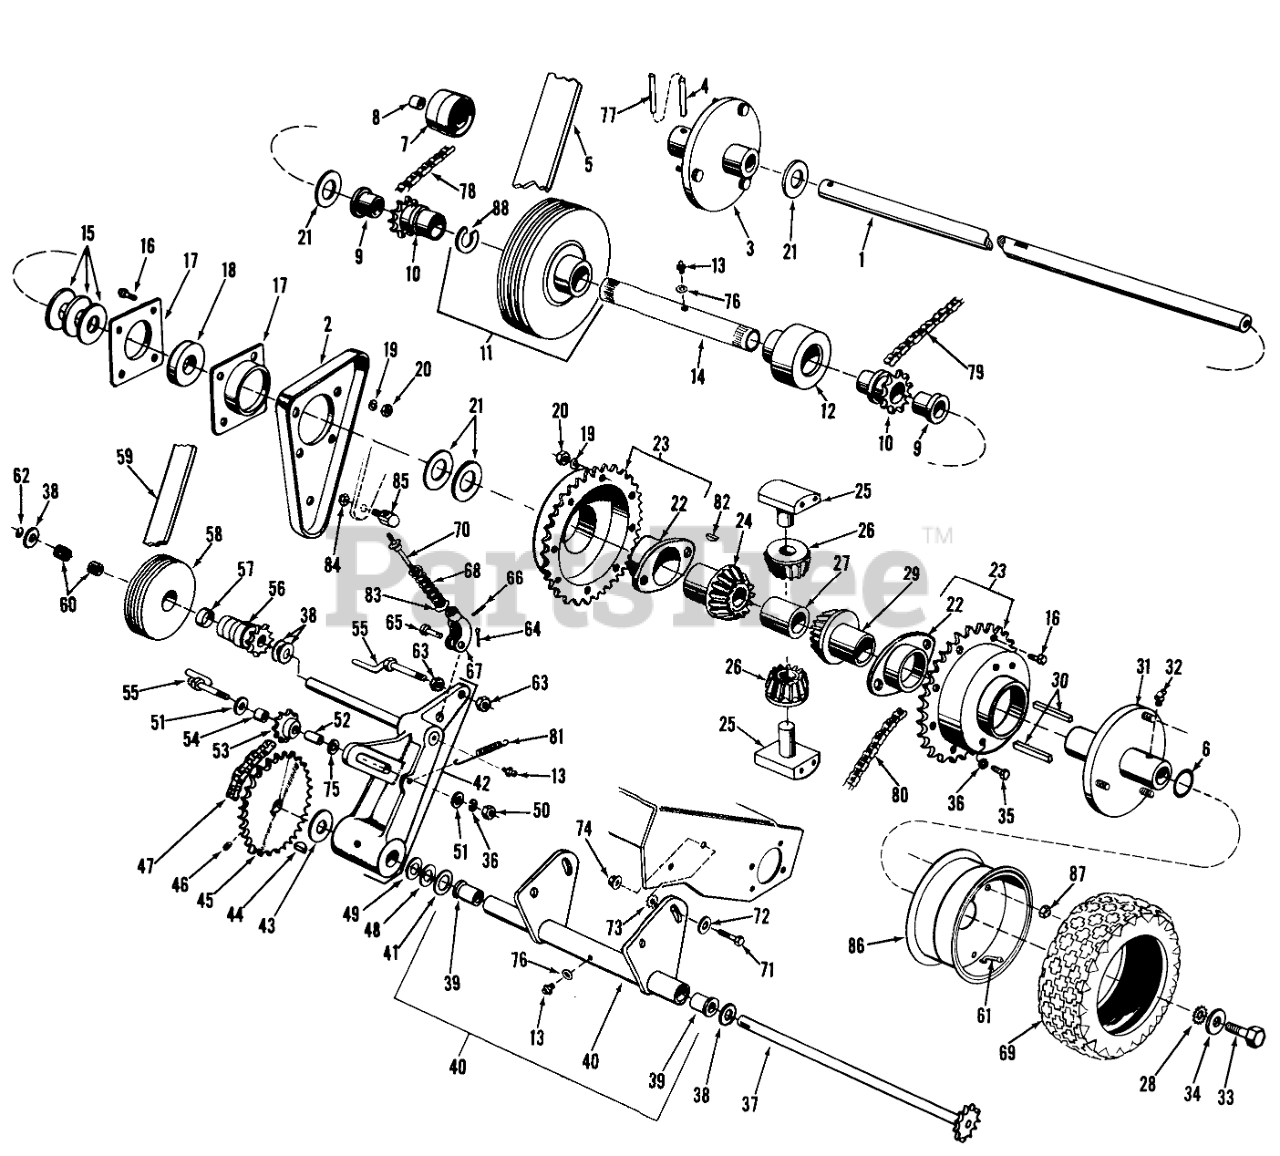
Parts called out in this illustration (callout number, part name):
3	Hub, Right Side
4	PIN-ROLL, SLOTTED
6	O-RING
7	REEL IDLER *R
8	TOL RING
9	3/4IDX1LG FLANGE BSHG
13	FITTING-GREASE
15	WASHER-THRUST
16	SCREW-HH
19	WASHER-LOCK
20	NUT-HEX
21	THRUST WASHER
28	WASHER-LOCK, INTERNAL
30	KEY-SQUARE
32	FITTING-LUBE, 45 DEG
33	SCREW-HH
34	WASHER-FLAT
35	SCREW-HH
36	WASHER-LOCK
38	THRUST WASHER
39	Bushing
41	Ring, Snap
42	Bell Crank Assy. (Incl. Ref. #13)
43	THRUST WASHER
44	KEY-WOODRUFF
45	LARGE SPROCKET ASM
47	TRACTION CHAIN
48	THRUST WASHER
49	THRUST WASHER
50	NUT-HEX
51	WASHER-PLAIN
52	SPINDLE
53	Sprocket, Idler w/Bearing
57	Ring Tolerance
58	TRACTION PULLEY
59	TRACTION BELT
60	.625 NEEDLE BEARING
62	Ring, Snap
63	NUT-JAM
64	PIN-COTTER
65	PIN-CLEVIS
66	PIN-ROLL, SLOTTED
67	CLEVIS
68	COMP SPRING *R
70	ROD FLANGE WA
71	SCREW-HH
72	WASHER-LOCK
73	WASHER-LOCK
75	WASHER-FLAT
76	WASHER-LOCK
77	PIN-ROLL
79	Chain, Reel Drive, Rear
81	SPRING-EXTENSION
82	KEY-WOODRUFF
83	WASHER-FLAT
84	NUT-LOCK, NI
87	LUG NUT
88	2-1/2X086 EX SNP RING
